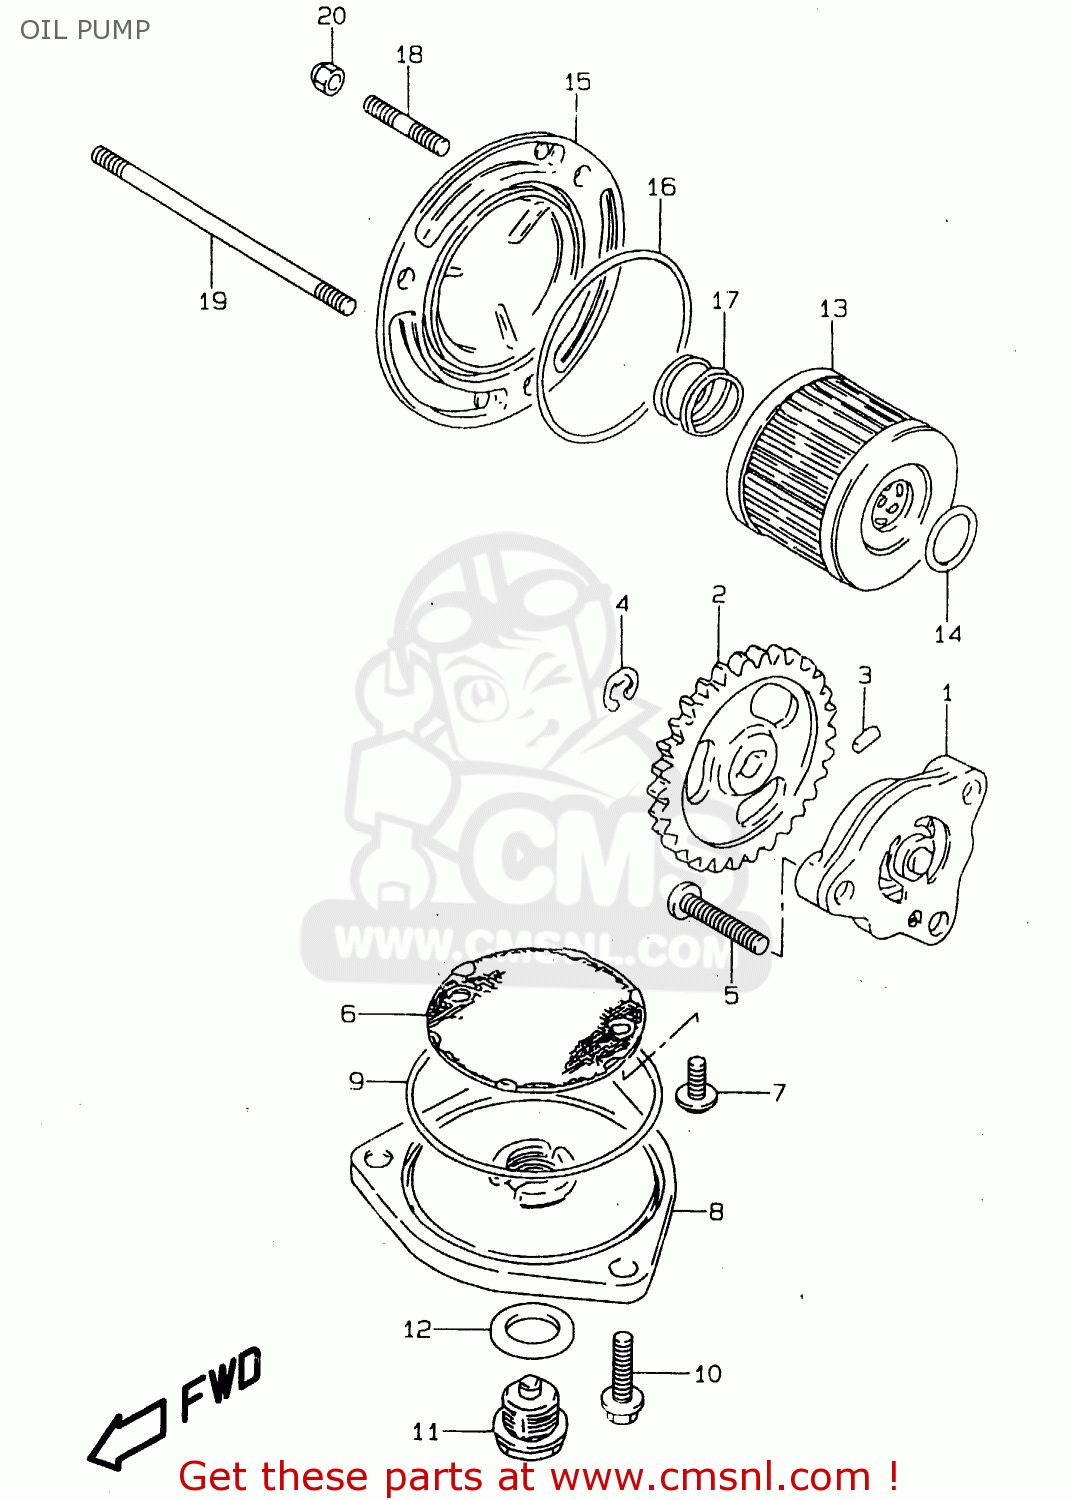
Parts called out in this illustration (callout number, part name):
1	PUMP ASSY,ENGINE OIL
2	GEAR,OIL PUMP DRIVEN
3	PIN(2.5X19.8)
4	E.RING
5	SCREW
6	STRAINER,ENGINE OIL
7	SCREW
8	CAP,OIL STRAINER
9	O RING(D:2.4,ID:60.5)
10	SCREW
11	PLUG(14X12)
12	GASKET(13.8X18.8X4.8) (NAS)
13	FILTER ASSY,ENGINE OIL
14	O RING(D:1.9,ID:13)
15	CAP,OIL FILTER
16	O RING(D:2.4,ID:52.6)
17	SPRING
18	STUD 6X12
19	STUD BOLT, 6X8
20	NUT
